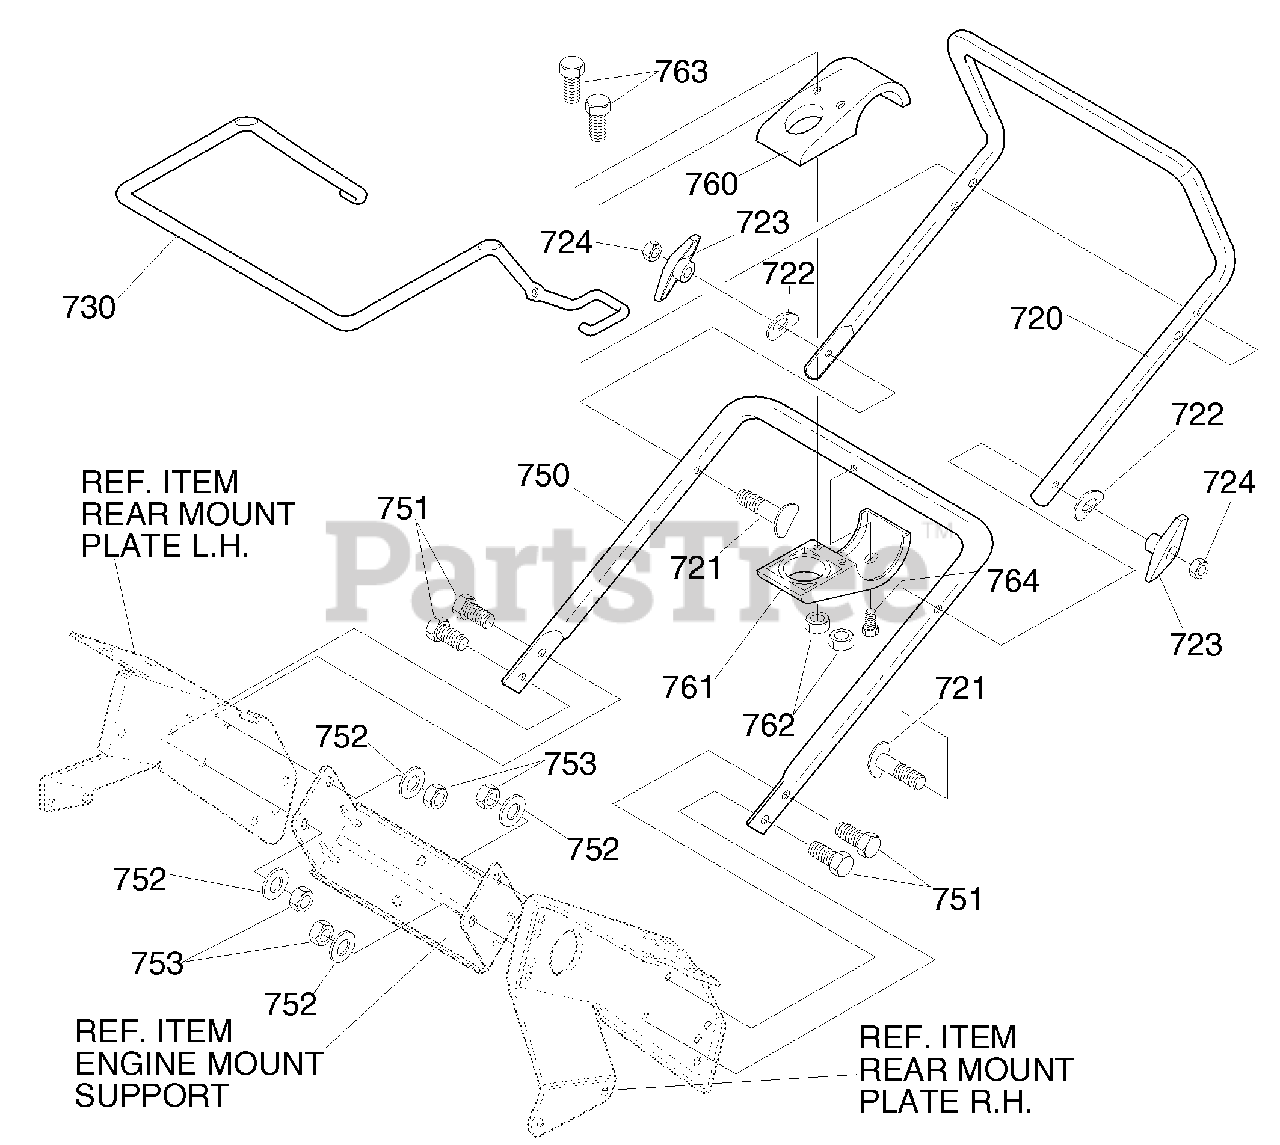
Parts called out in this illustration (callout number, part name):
720	HANDLE, UPR .88 X 18GA
721	BOLT, 5/16-18 X 1.75
722	WASHER, FORM .344 ID 1.0 OD
723	KNOB, T 2BLADE W/NUT
724	NUT, 5/16-18 REGHEX
730	BAR, CONTROL DRIVE .31 DIA
750	HANDLE, LWR
751	SCREW, 5/16-18 X .75 HHC
752	WASHER, FLAT
753	NUT, 5/16-18 REGHEXCTRLK
760	BRKT HALF, CHUTE CRANK
761	BRKT HALF, CHUTE CRANK
762	NUT, #10-24 HEXNYLK
763	SCREW, 010-24 X 1.00
764	SCREW, 1/4-20 X .63
